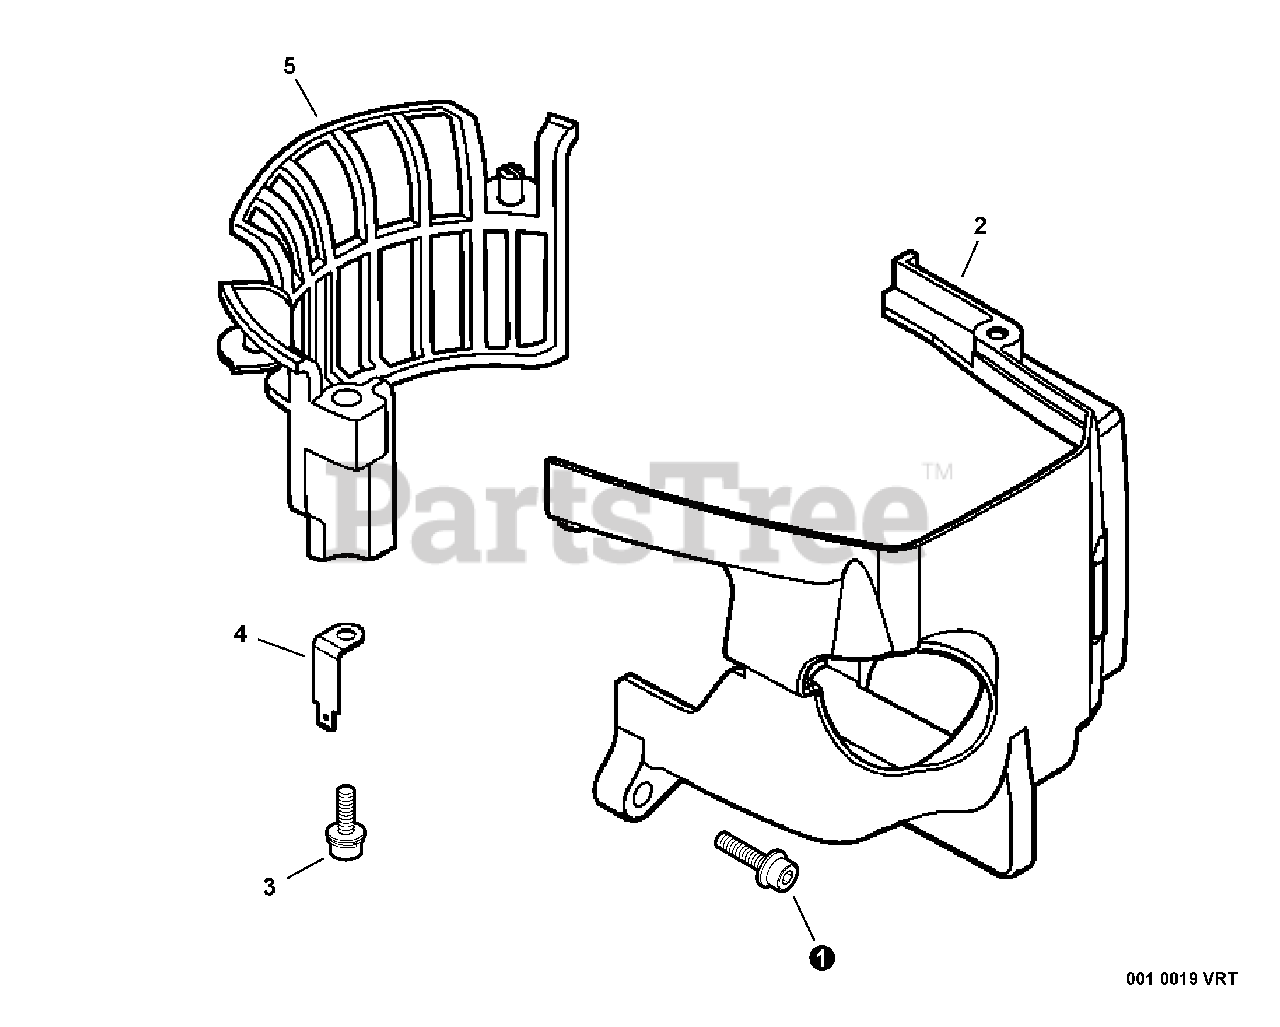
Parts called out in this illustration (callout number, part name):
1	SCREW - 5X16
2	COVER, ENGINE
3	SCREW - 5X16
4	TERMINAL - GROUND
5	GUARD, DEBRIS
